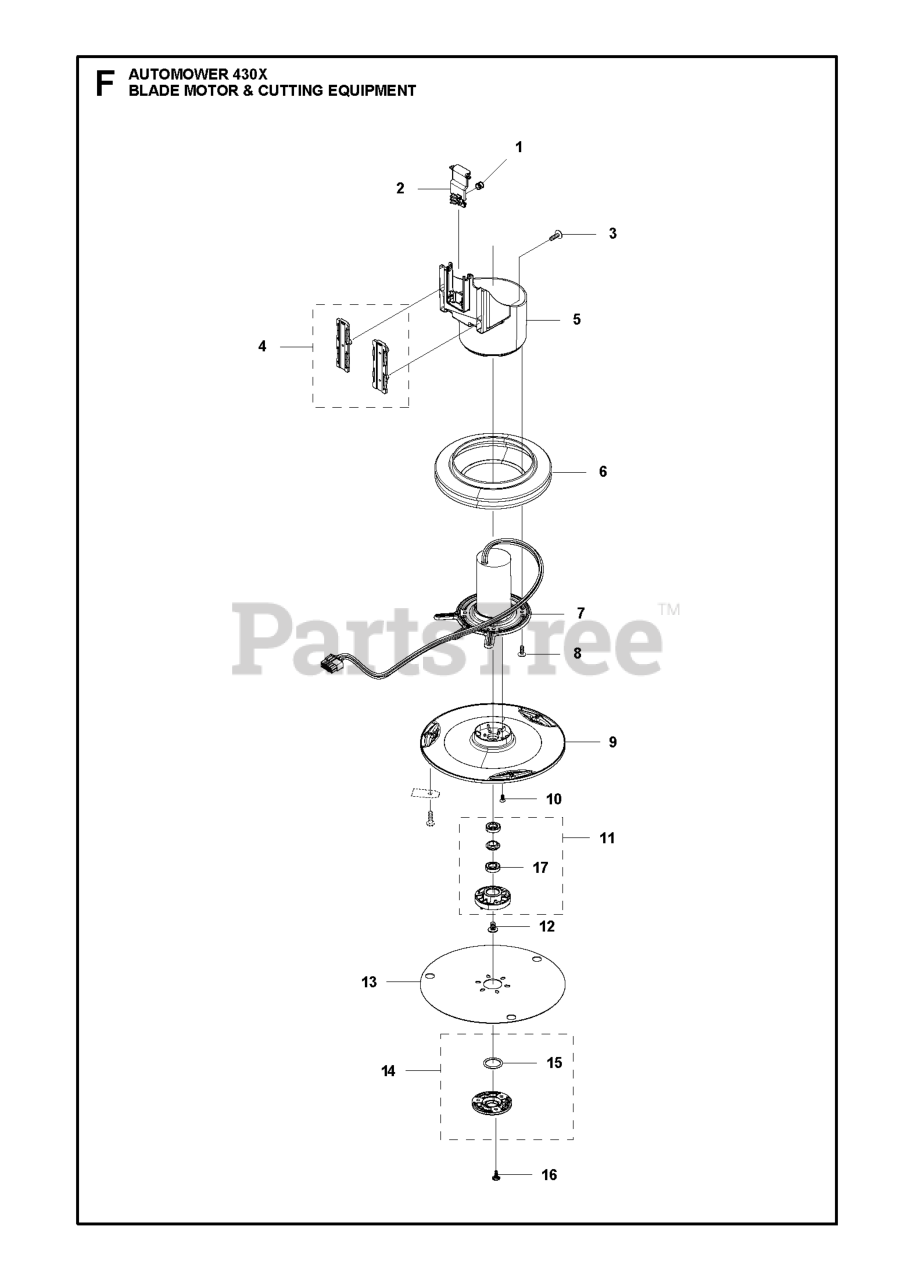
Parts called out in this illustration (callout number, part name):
1	SPRING LINK
2	LINK MOTOR HOUSING
3	SCREW 14MM
4	BEARING KIT
5	HOUSING CUTTING MOTOR
6	BELLOWS CUTTING SYSTEM
7	MOTOR ASSY JE
8	SCREW 14MM
9	CUTTING DISC
10	SCREW TORX M4X8 8.8 NYLON PATC
11	BEARING HOUSING ASSY SPARE PAR
12	SCREW
13	SKID PLATE
14	COVER KIT BEARING
15	O-RING 20X2,5 MM
16	SCREW 14MM
17	BALL BEARING 2 RS,TIGHT CLEAR
17	BALL BEARING BALL BEARING 535
